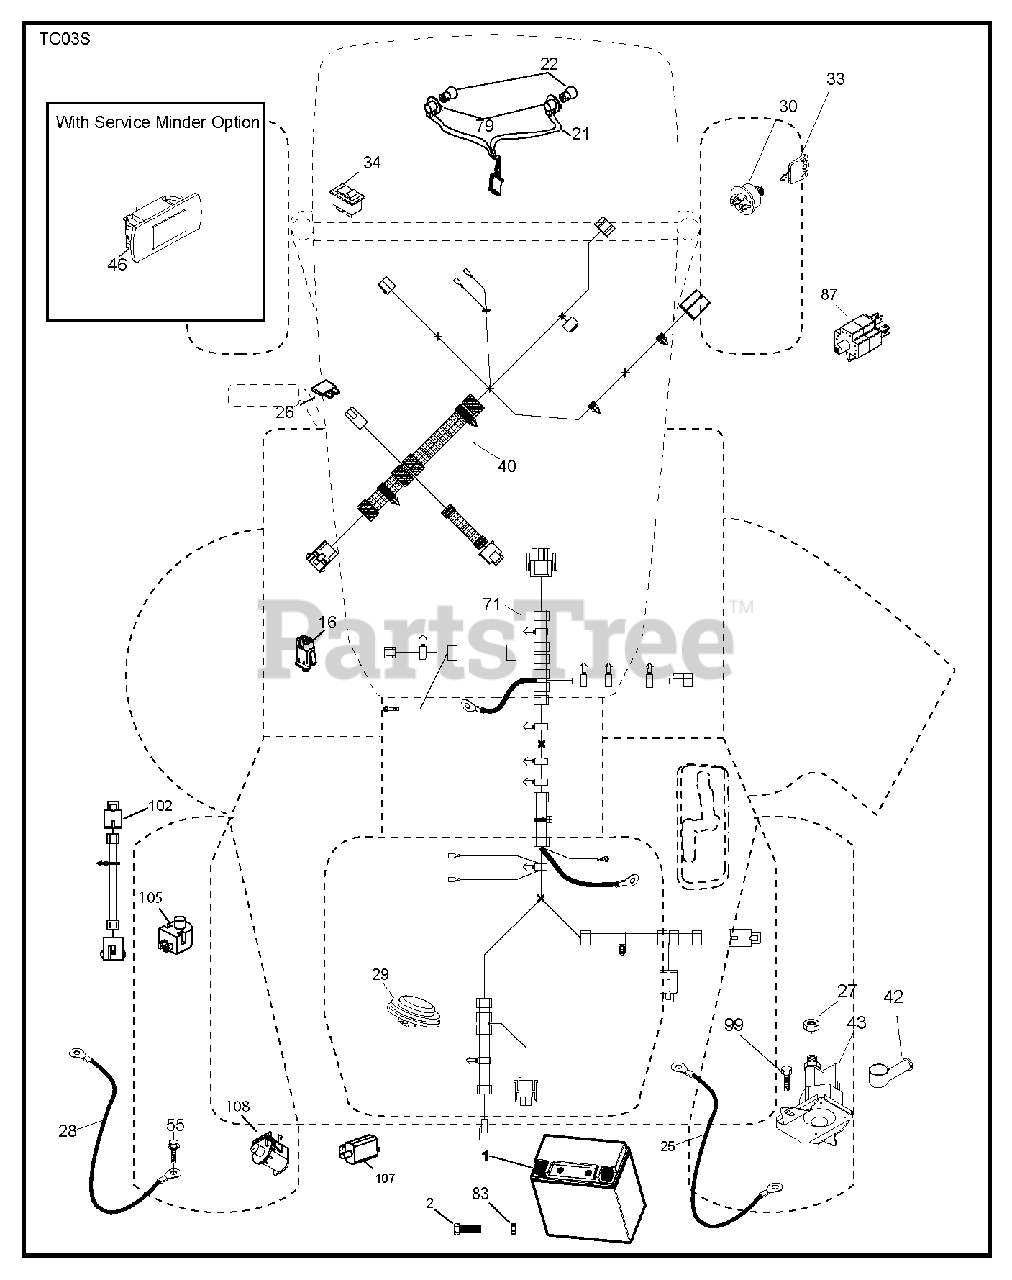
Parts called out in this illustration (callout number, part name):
1	BATTERY BATTERY 14AH 12V LEOC
2	SCREW.HEX.HEAD.CAP.M6 X1.12W
16	SWITCH INTERLOOK PUSH-IN
21	HARNESS.LIGHT W/4152J BULBS
25	CABLE BATTERY CABLE
26	FUSE 20AMP
27	NUT
29	SWITCH.SEAT.DELTA.OPC.
30	SWITCH.IGN.DELTA.W.LGH.ROS
33	KEY.CHAIN.BLISTER.PACK.GEN.INT
40	RP HARNESS.ELECTRICAL.DASH.SRD
42	TERMINAL COVER
43	SOLENOID.W/BRASS.PLUNGER
46	RP GUAGE.SRVCMNDR.HRMTR.
55	SCREW 5/16"
71	HARNESS
79	BULB HOLDER ASM.
83	NUT NUT SQUARE
87	RP SWITCH.RAILMOUNT.NO-NC-NC
99	SCREW
102	HARNESS PIGTAIL PCH TEX ROS
105	REVERSE SWITCH
107	.WITCH.FULL BAGGER.INDICATOR
108	SWITCH.SNAPMOUNT.NC
